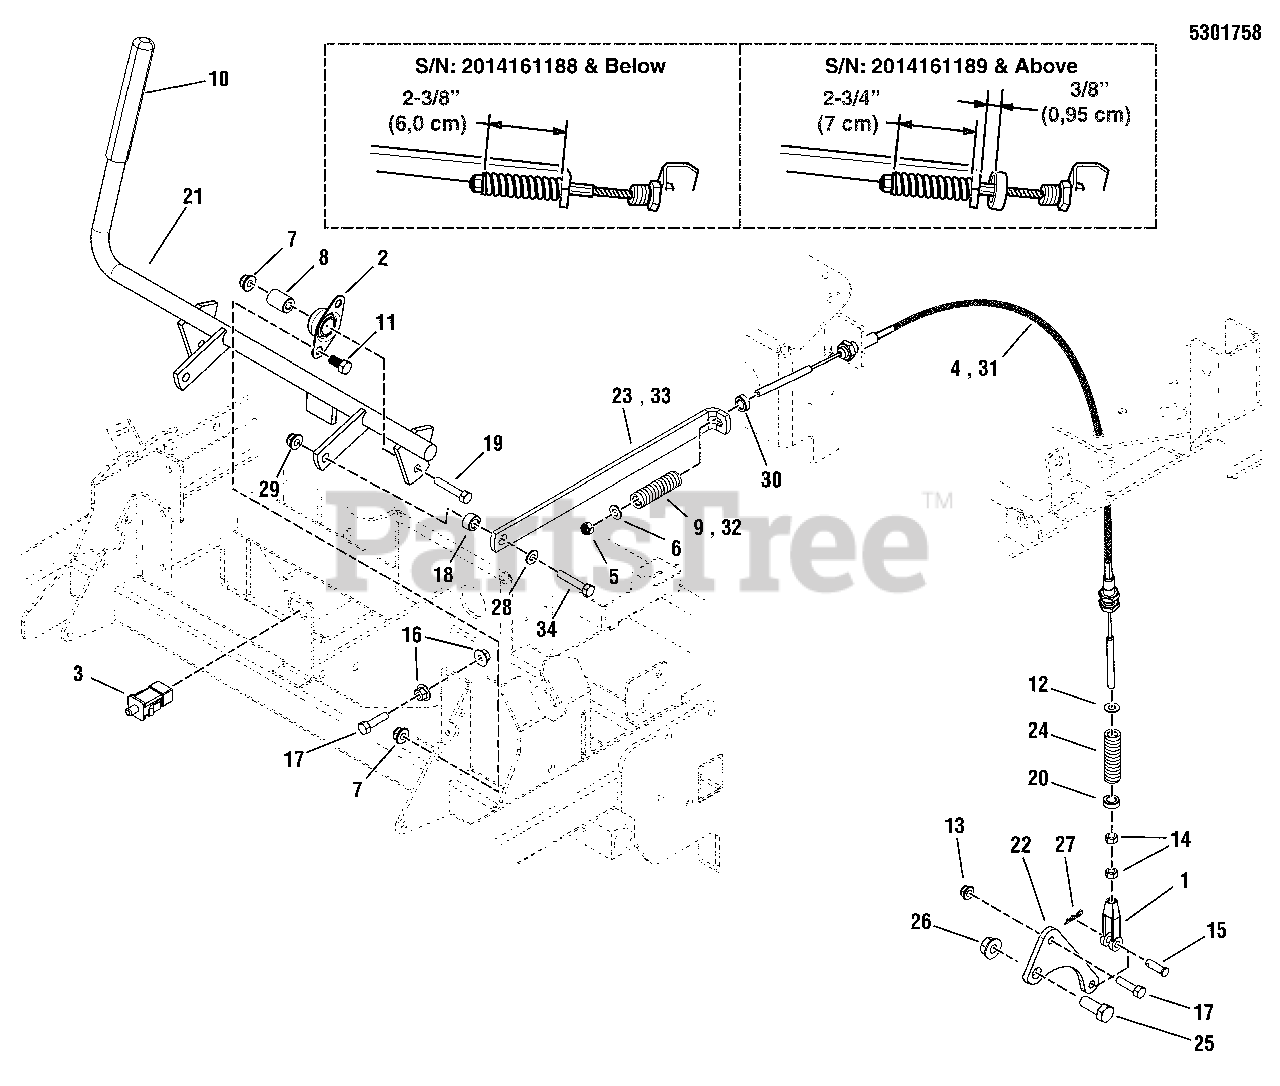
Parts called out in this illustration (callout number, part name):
1	CLEVIS, 5/16-24, STEEL, CLEAR ZINC
2	BEARING, BRONZE FLANGE, 3/4
3	SWITCH, DP NO/NC SNAP-IN
4	CABLE, PARKING BRAKE
5	NUT, 5/16-24 HEX NYLON LOCK
6	WASHER, 5/16" SAE
7	NUT, 3/8-16 HEX NYLOCK FLANGE
8	SPACER, .32 X .75 X 1.06
9	SPRING-COMP, .75 X .162 X 2.5
10	GRIP, FOAM, 3/4 ID X 6 X .187
11	BOLT, 5/16-18 X 3/4 GD5
12	WASHER, 1/2 USS
13	NUT, 5/16-18 HEX NYLON LOCK
14	NUT, 5/16-24 HEX
15	PIN-CLEVIS, 5/16 X 1 YZ
16	NUT, 5/16-18 HEX SERRATED FLANGE (LARGE)
17	BOLT, 5/16-18 X 1-1/4 GD5 YZ
18	SPACER, .38 X .50 X .31, CZ
19	BOLT, 5/16-18 X 1-3/4 GD5 YZ
20	BUSHING, DECK PIVOT
21	WELD, BRAKE SHAFT - BLK
22	PLATE, BRAKE ARM EXTENSION - BLK
23	LINK, BRAKE LOCK - RED
24	SPRING, COMP, 1.1 X OD. X .085 WIRE X 5
25	BOLT, 1/2-13 X 1-1/4 GD5 CZ
26	NUT, 1/2-13 HEX SIDE LOCK
27	PIN, COTTER, 1/8 X 3/4
28	WASHER, 3/8 SAE
29	NUT, 3/8-16 HEX SIDE LOCK
30	COLLAR, 5/16 SET
31	CABLE, PARKING BRAKE, S200XT
32	SPRING, COMP. 1/2 ID X .140 WIRE X 3.25
33	LINK, BRAKE LOCK - BLK
34	BOLT, 3/8-16 X 1-1/4" GD5 CZ
